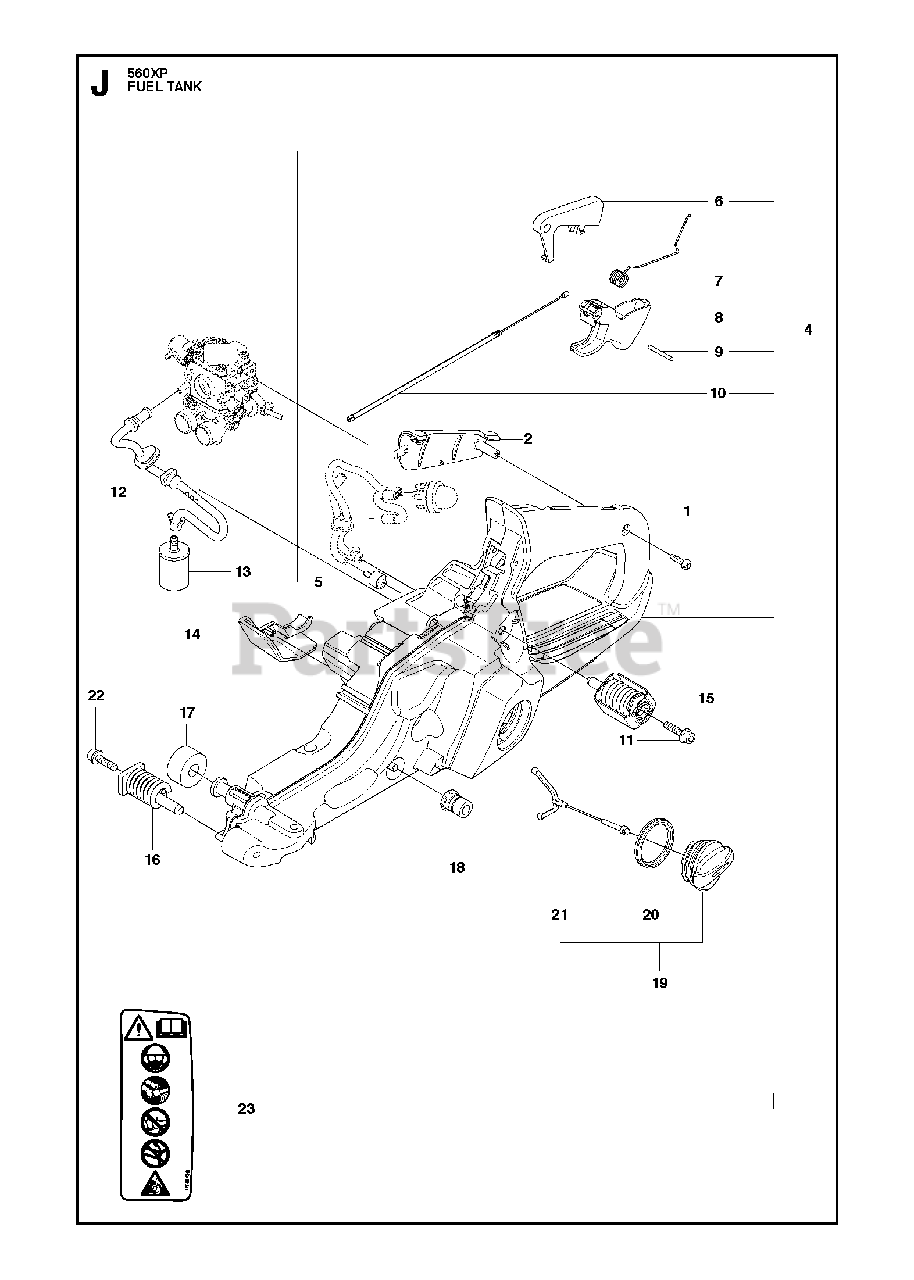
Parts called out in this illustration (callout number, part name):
2	HANDLE INSERT
4	FUEL TANK ASSY
5	FUEL TANK VENT
6	THROTTLE LOCKOUT
7	SPRING
8	THROTTLE
10	THROTTLE CABLE ASSY
13	FUEL FILTER
15	ANTIVIBRATION ELEMENT
16	ANITVIBRATION ELEMENT
17	DEFLECTION LIMITER
18	LATERAL SUPPORT
19	TANK CAP ASSY
20	SEALING
21	HOLDER
23	DECAL
